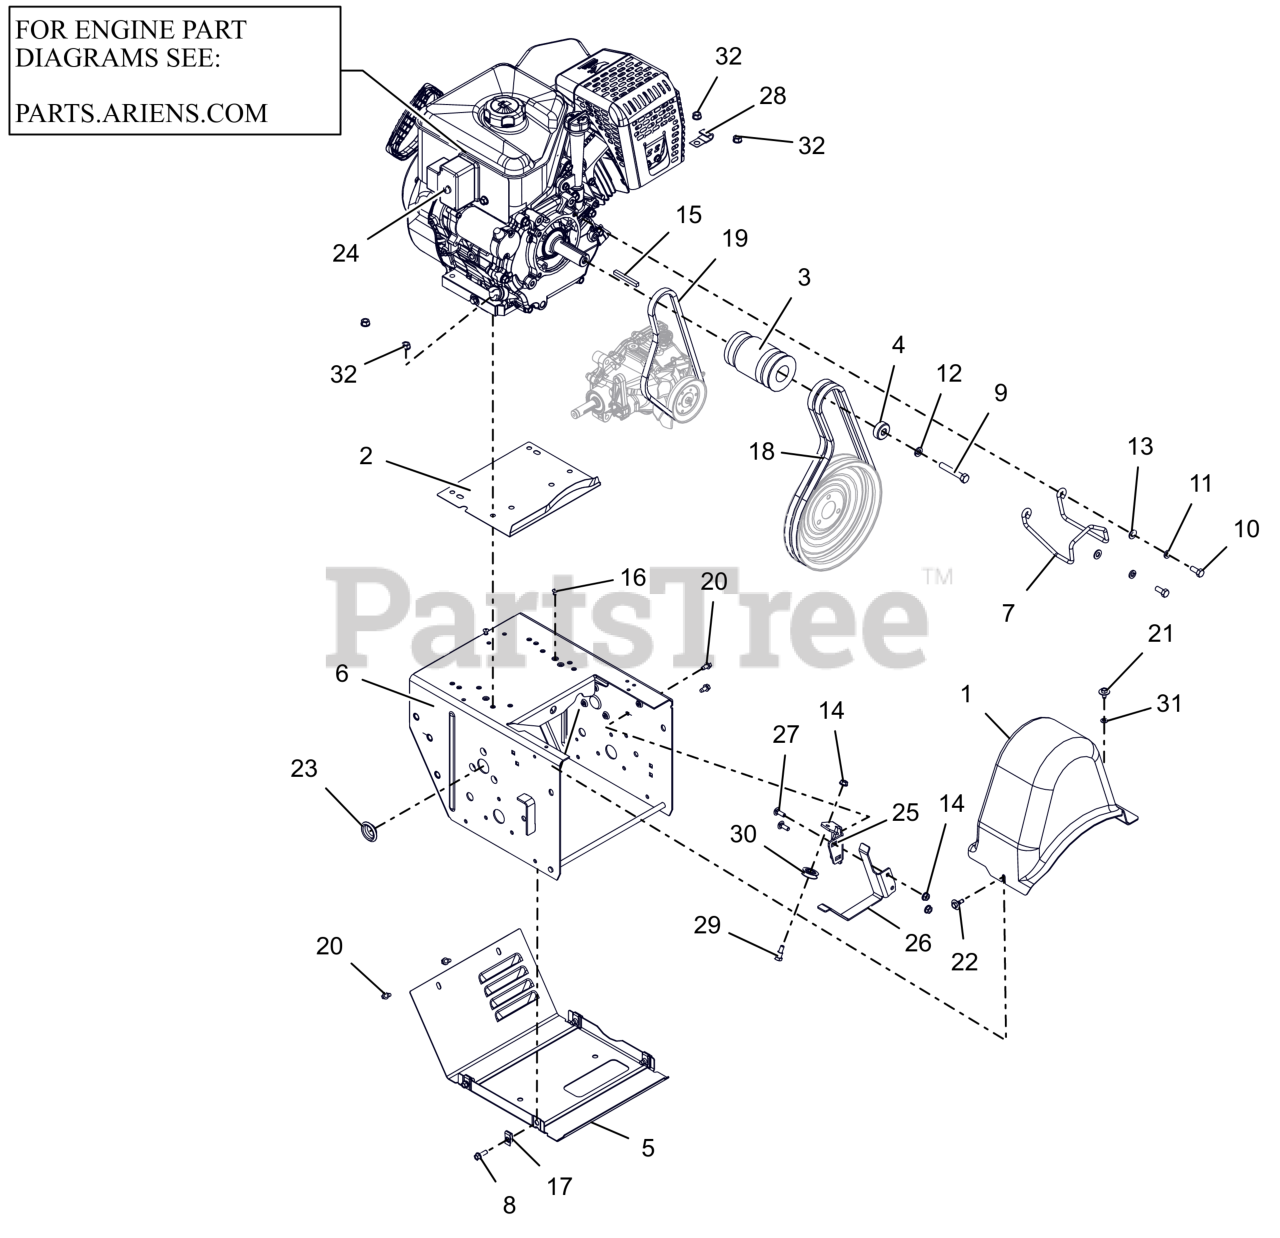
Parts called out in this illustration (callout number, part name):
1	COVER, BELT-LARGE
2	BAFFLE, WATER - LARGE BLOCK
3	SHEAVE, COMBO HYDRO WHEEL 4L
4	BSHG, SPCR .406 X 1.250 X .500
5	COVER, BOTTOM - VENTILATED
6	FRAME, MAIN - PRO (WELDMENT)
7	FINGER, BELT
8	BLT, HWH .25-20X.75 G5 ZCC
9	BLT, HEX .38-24X2.25 G5 ZCC
10	BLT, HEX .31-24X.750 G5 ZCC
11	WSHR, LK-HVY .312X.097 ZCC
12	WSHR,LK-REG .375X.094 ZCC
13	WSHR,FLT .344X.688X.065 ZCC
14	NUT-LK-TOP-FLG .250-20 GF ZCC
15	KEY .25X.25X2.25
16	RVT, POP .1875 ZCC
17	NUT-RTNR .25-20X.56
18	V-BELT, HA-RAW EDGE (SET)
19	V-BELT, 4L-WRAPPED
20	SCR-TAP .25-20X.50 HWH ZCC
21	SCR, TAP .25-20X.50 LG HWH ZCC
22	SCR-TAP .25-20X.5 CAPTIVE
23	PLUG, HOLE - 1.125"
24	ENGINE, EFI 420 GEN 3 240V/60W
25	BRACKET, CLUTCH CABLE
26	FINGER, BELT - FLAT
27	BLT, RHSN .25-20X.750 G5 ZCC
28	J-CLAMP
29	BOLT, SHLDR -.375 X .375 X .25-20
30	PULLEY, CABLE
31	NUT-PUSH .25X.50 O.D.
32	NUT,LK-CTR-FLG .31-18 GF ZCC
